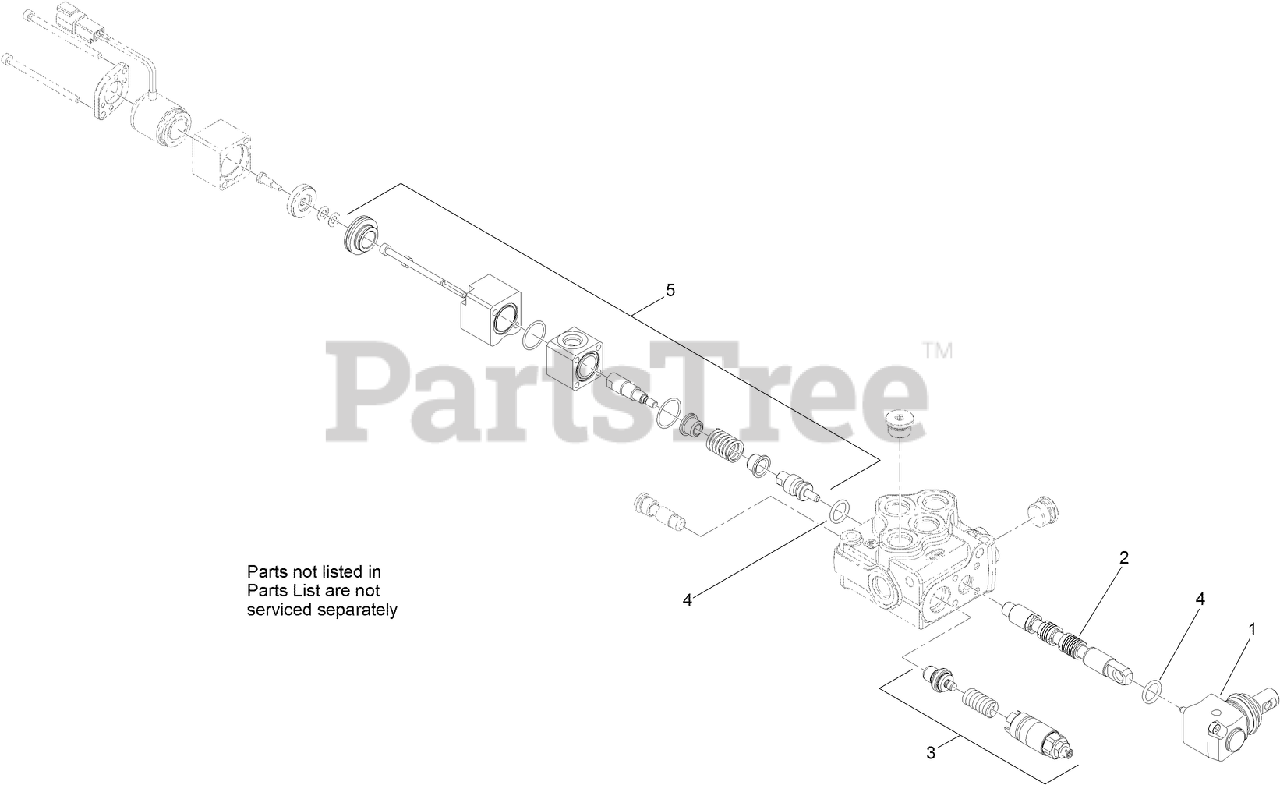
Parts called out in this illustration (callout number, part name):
1	LEVER KIT (WITH SCREWS)
2	VALVE-SPOOL
3	VALVE-RELIEF
4	SEAL-VALVE
5	SPRING KIT
